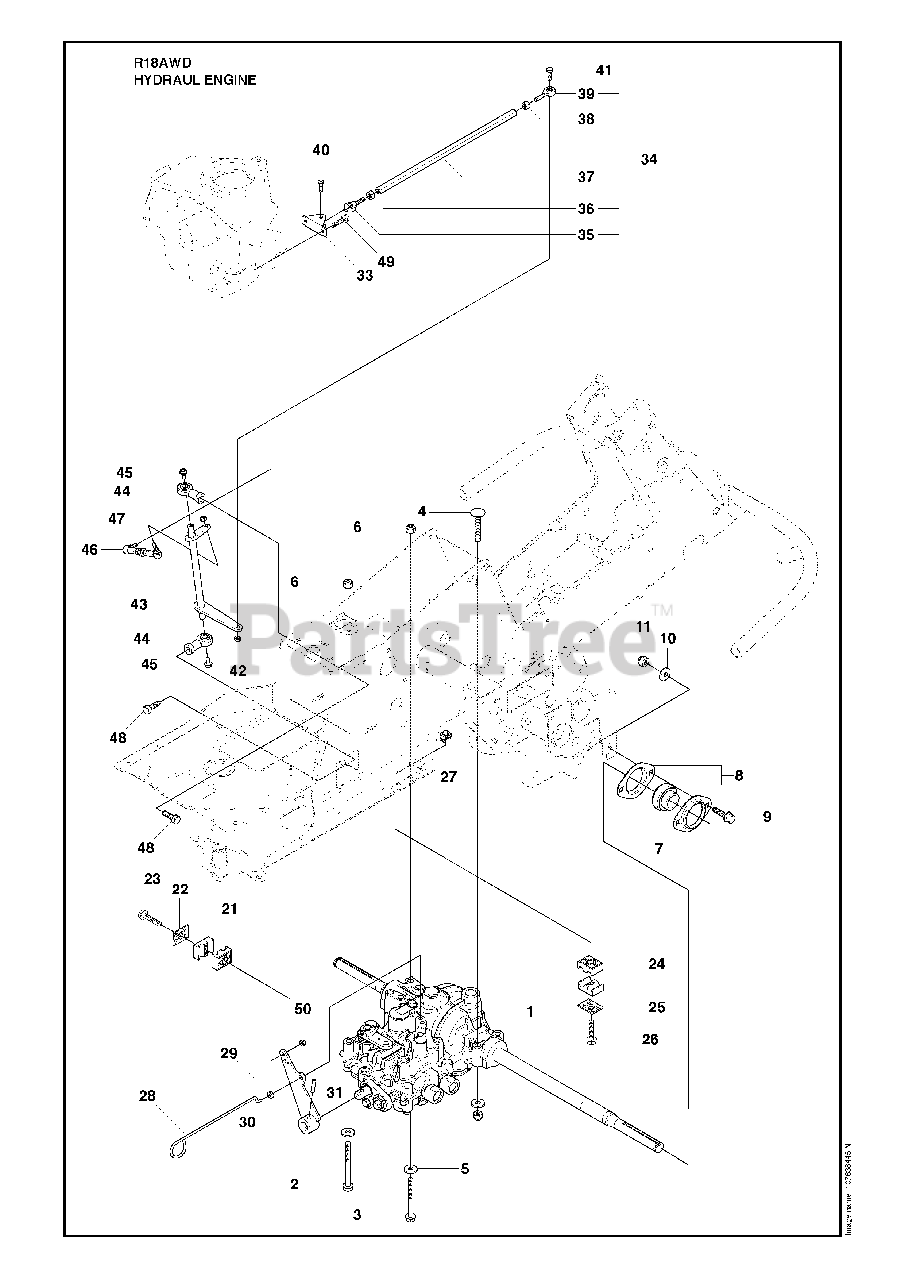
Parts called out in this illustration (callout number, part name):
1	TRANSMISSION SWE
5	WASHER BRB 8.4X17
6	LOCKNUT M8
8	BEARING HOUSING
9	BOLT
10	WASHER BRB 8.4X17
11	LOCKNUT M8
12	PIPE FITTING
15	HYDRAULIC PIPE
16	HYDRAULIC PIPE
17	HYDRAULIC HOSE
20	HOSE GUARD D=43 L=400
21	PIPE CLAMP
24	PIPE CLAMP
25	COVER PLATE
26	SCREW EHHFM
29	FUEL TANK BUSHING
34	ROD
42	NUT FLANGE - M6
45	SCREW EHHFM
46	ADJUSTING ROD
47	NUT FLANGE - M6
48	Screw, M10 X 25
50	LOCKNUT M6
